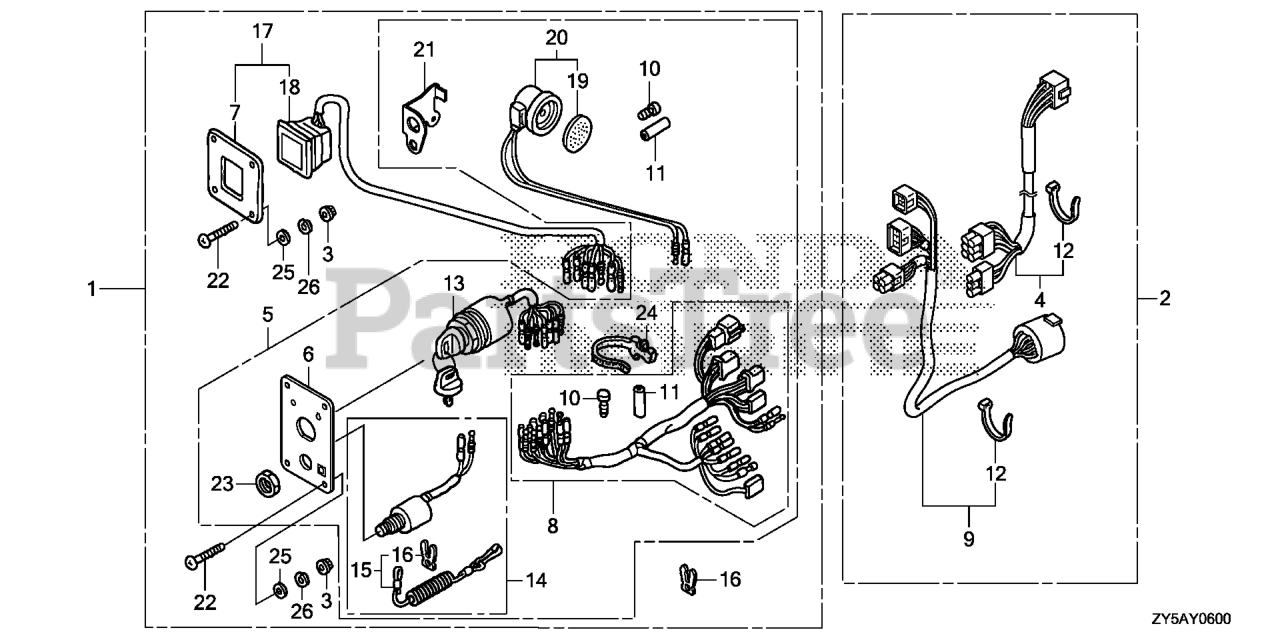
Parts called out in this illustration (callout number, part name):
1	PANEL KIT, SWITCH (4-LED) (B)
2	CABLE SET, PANEL INDICATOR (20FT)
2	CABLE SET, PANEL INDICATOR (25FT)
2	CABLE SET, PANEL INDICATOR (30FT)
3	NUT, FLANGE (5MM) DUAL QTY = (8) (SINGLE)
3	NUT, FLANGE (5MM)
4	WIRE ASSY., INDICATOR (20FT)
4	WIRE ASSY., INDICATOR (25FT)
4	WIRE ASSY., INDICATOR (30FT)
5	PANEL ASSY., SWITCH
6	PANEL, CONTROL
7	PANEL, CONTROL
8	HARNESS ASSY., SWITCH PANEL
9	CABLE ASSY., SWITCH PANEL (20FT) (NHK MEC)
9	CABLE ASSY., SWITCH PANEL (25FT) (NHK MEC)
9	CABLE ASSY., SWITCH PANEL (30FT) (NHK MEC)
10	PLUG, CONNECTOR (INNER) (TROLLING CONTROL)
11	PLUG, CONNECTOR (OUTER) (ENGINE NO.)
12	TIE, CABLE (NATURAL 2.4X92) Use up to Frame SN 1300359.
13	SWITCH ASSY., COMBINATION (SINGLE) (DUAL)
14	SWITCH ASSY., EMERGENCY STOP
15	WIRE, EMERGENCY (SINGLE) (DUAL)
16	CLIP, EMERGENCY LOCK
17	PANEL ASSY., INDICATOR (4-LED)
18	LAMP ASSY., INDICATION (4-LED)
19	PLATE, TURN SIGNAL BUZZER DUAL QTY = (2) (SINGLE)
20	BUZZER, WARNING DUAL QTY = (2) (SINGLE)
21	BRACKET, BUZZER
22	SCREW, PAN (5X40) DUAL QTY = (8) (SINGLE)
23	NUT, HEX. (16MM) DUAL QTY = (2) (SINGLE)
24	BAND, WIRE HARNESS (150MM) (NATURAL) DUAL QTY = (2) (SINGLE)
25	WASHER, PLAIN (5MM)
25	WASHER, PLAIN (5MM) DUAL QTY = (8) (SINGLE)
26	WASHER, SPG (5MM)
26	WASHER, SPRING (5MM) DUAL QTY = (8) (SINGLE)
